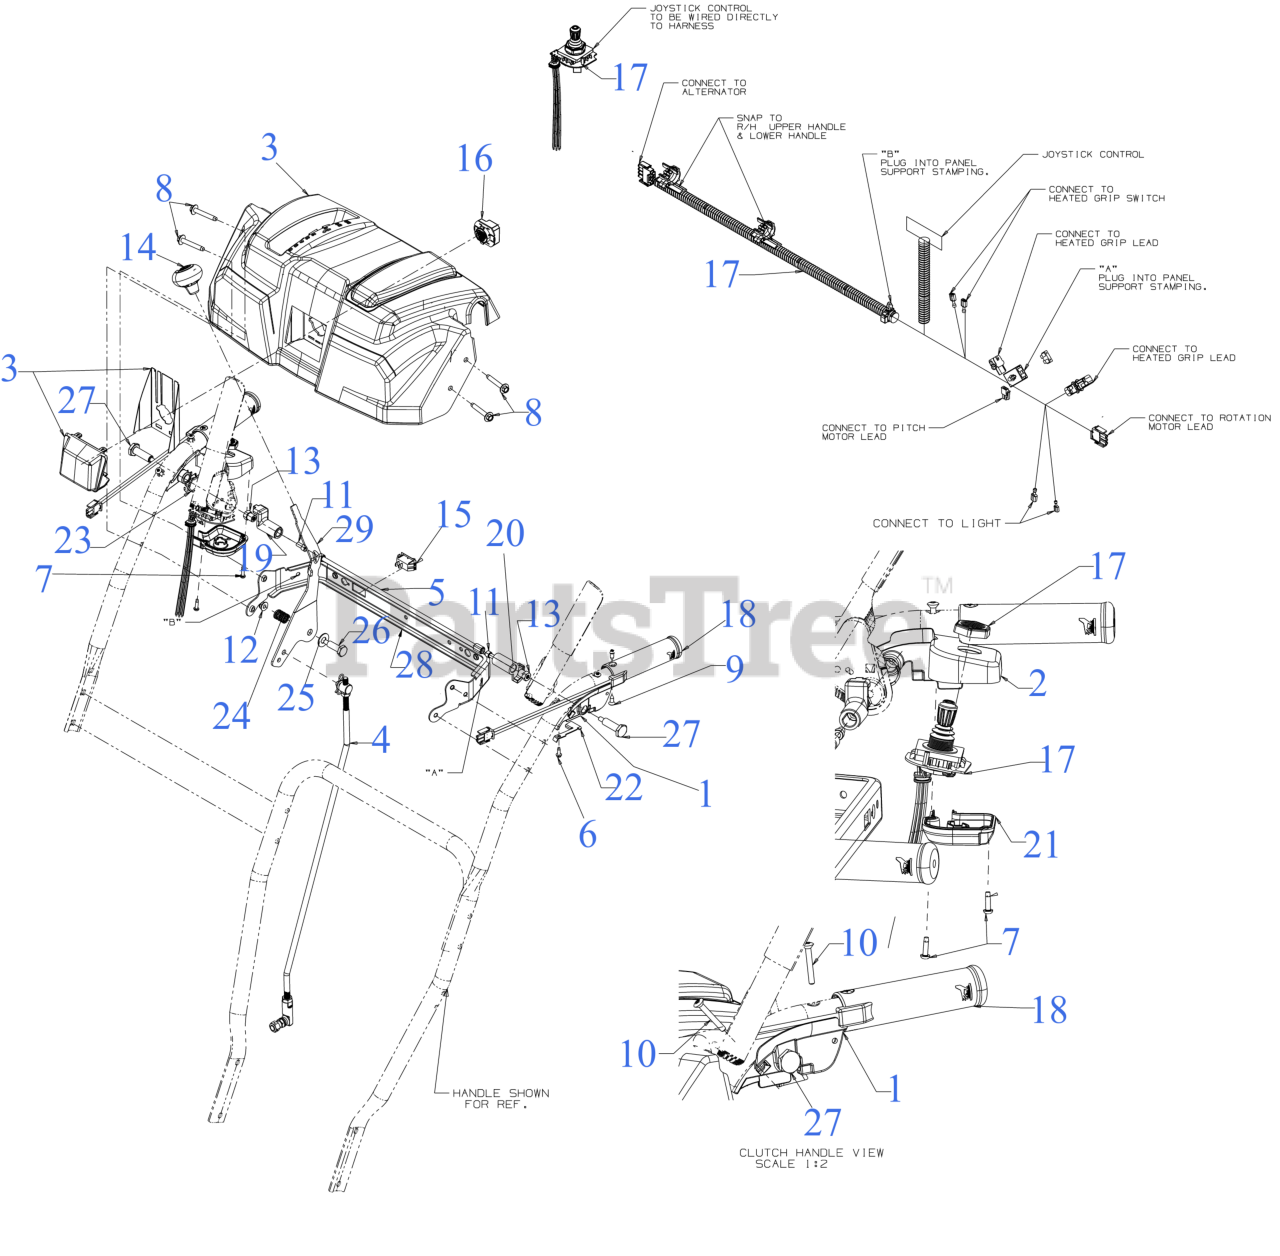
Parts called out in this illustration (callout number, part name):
1	CLUTCH LOCK HANDLE ASSEMBLY (LH)
2	CLUTCH HANDLE ASSEMBLY (RH)
3	HANDLE PANEL ASSEMBLY
4	SHIFT ROD ASSEMBLY
6	SCREW #8-16 x .50
7	SCREW .159 x .610
8	SCREW 1/4-20 x 1.625
9	SCREW-AB #12-24 x .625
10	SCREW #10-24 x 1.375
11	SCREW 1/4-20 x .50
12	FLANGE LOCK NUT
13	HEX NUT W/PATCH
14	SHIFT KNOB
15	HEATED GRIP SWITCH
16	LED HEADLIGHT & SOCKET (150 LUMNES)
17	4-WAY ELEC/HEAT GRIP HARNESS
18	HEATED GRIP
20	CLUTCH LOCK CAM
21	JOYSTICK HOUSING COVER
22	CLUTCH SPRING
23	TORSION SPRING
24	COMPRESSION SPRING
25	FLAT WASHER .38X.88
25	FLAT WASHER .401X.88
26	SHOULDER SCREW
27	SHOULDER SCREW .437 x 1.345 1/4-20
